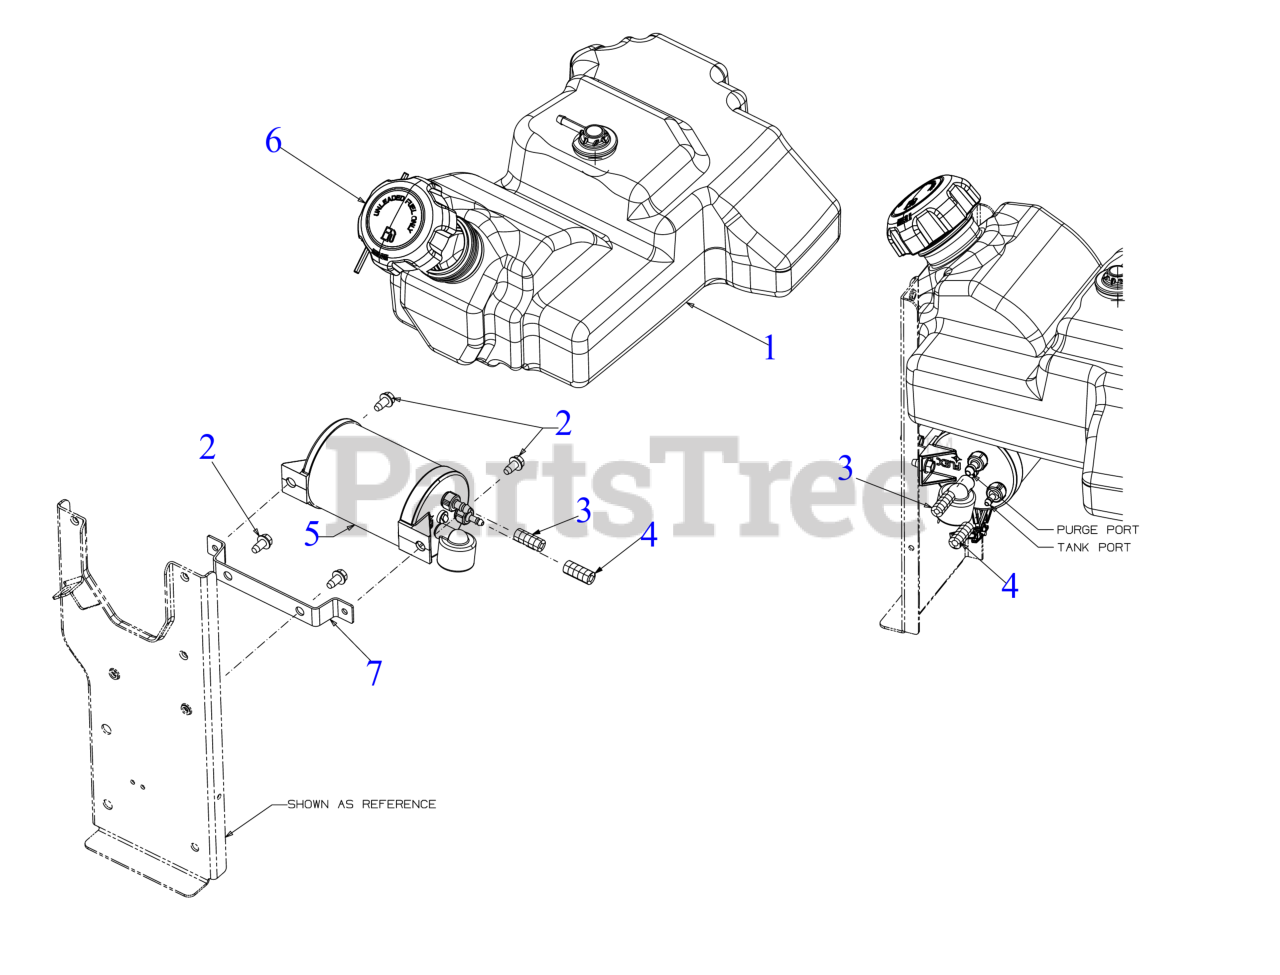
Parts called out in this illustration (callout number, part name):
1	FUEL TANK ASSEMBLY 1 GAL
1	ROLLOVER FUEL VALVE
1	RUBBER GROMMET 23.0 ID x 35.5 OD
2	SCREW 1/4-20 X.500
3	FUEL HOSE LO PERMEATION 30"
4	FUEL HOSE LO PERMEATION 28"
5	CARBON CANISTER
6	FUEL CAP W/TETHER
